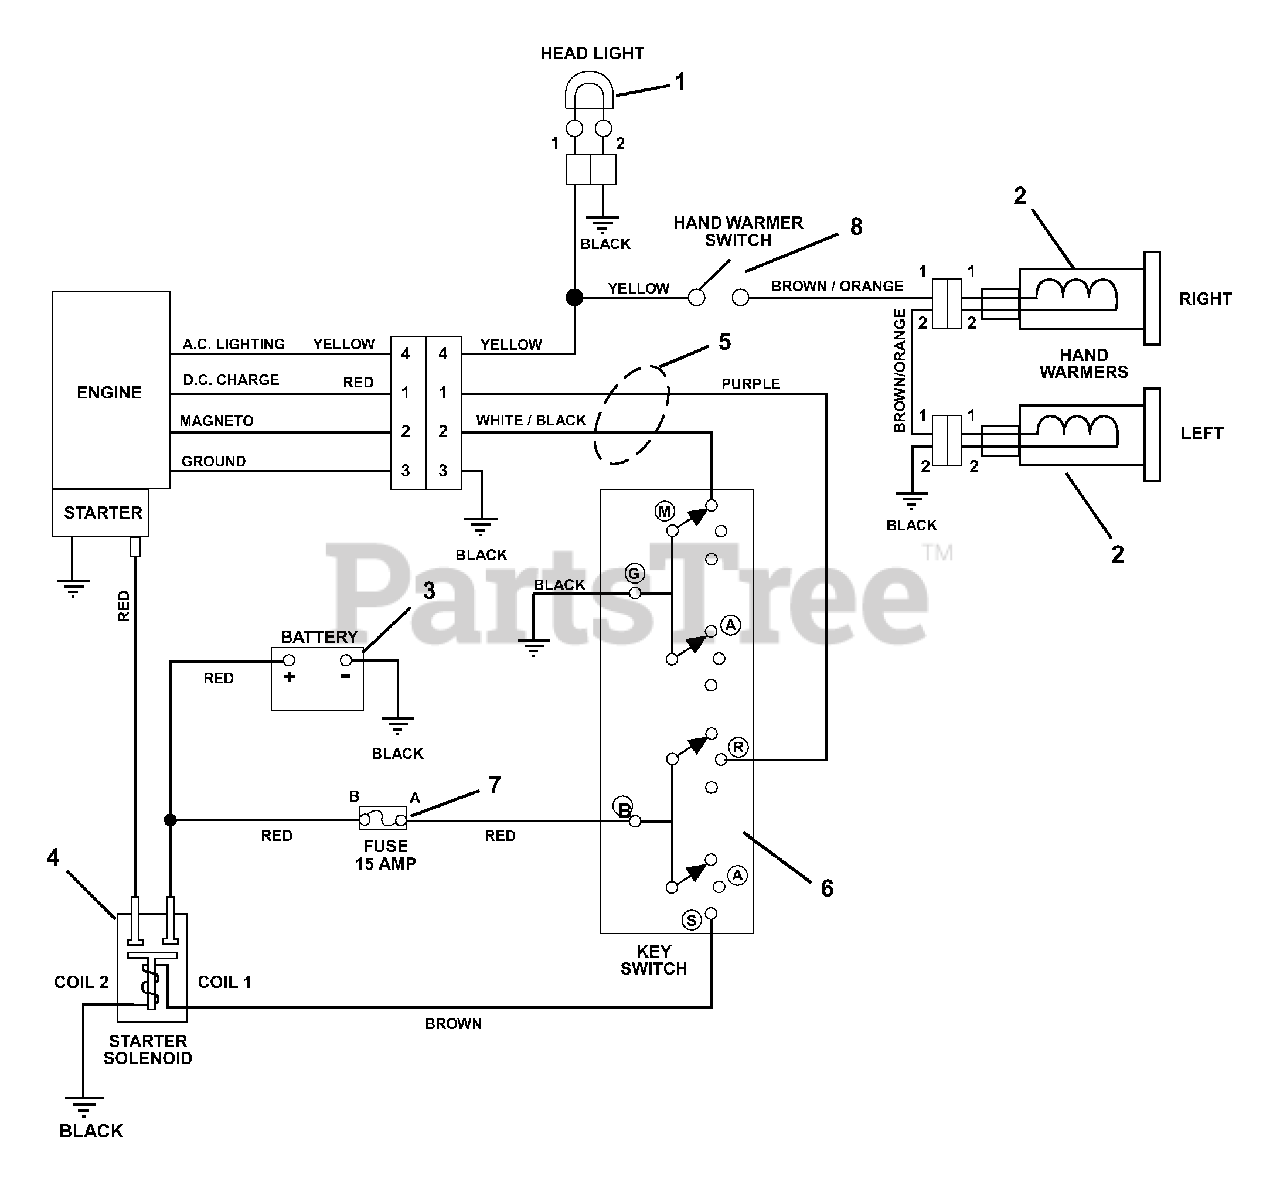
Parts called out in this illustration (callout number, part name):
1	HEADLAMP, OVAL W/ 1156 BULB
2	WARMER, HAND W/TERMINAL
4	SOLENOID
5	HARNESS, WIRE - LT,HW,12V
6	SWITCH ASSEMBLY
7	FUSE, 15 AMP.
8	SWITCH, ON/OFF
